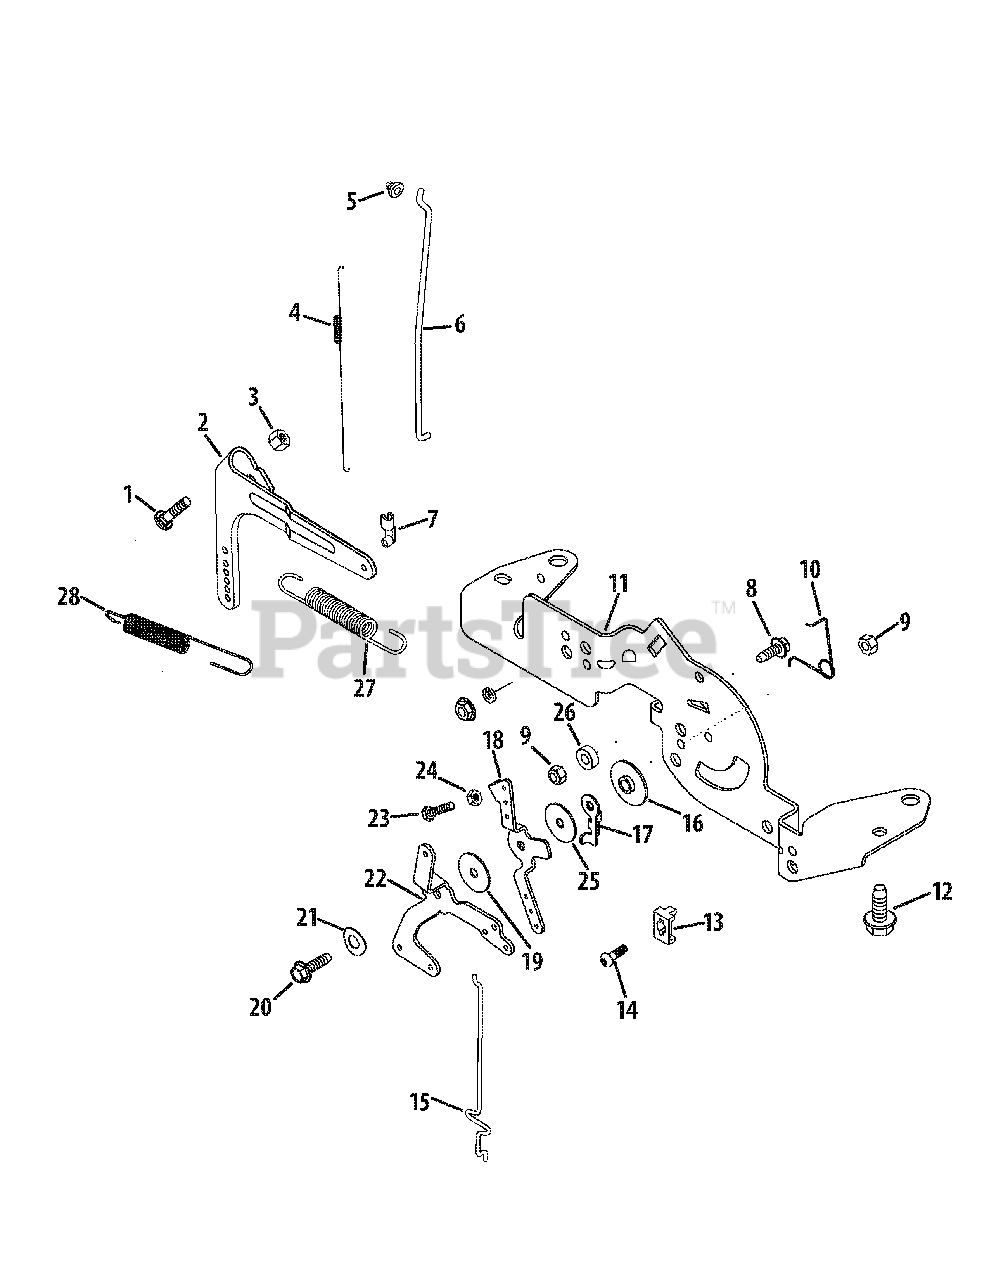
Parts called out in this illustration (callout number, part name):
1	Bolt, M6 x 1.0 x 25
2	Governor Lever
3	Flange Nut, M6 x 1.0
4	Linkage Spring
5	Linkage Retaining Bushing
6	Throttle Linkage
7	Throttle Linkage Bushing
8	Flange Screw, M5 x .8 x 16
9	Lock Nut, M5 x 8
10	Choke Return Spring
11	Control Bracket
12	Flange Screw, M6 x 1.0 x 16
13	Cable Clamp
14	Screw, M5 x .8 x 16
15	Choke Linkage
16	Control Assembly Spacer
17	Throttle Actuator Lever
18	Throttle Control Lever
19	Flat Washer, 5.5mm
20	Flange Screw, M5 x .8 x 20
21	Spring Washer, 1/4
23	Screw, M4 x .7 x 25
25	Flat Washer, 5mm
27	Governor Spring
28	Governor Spring
